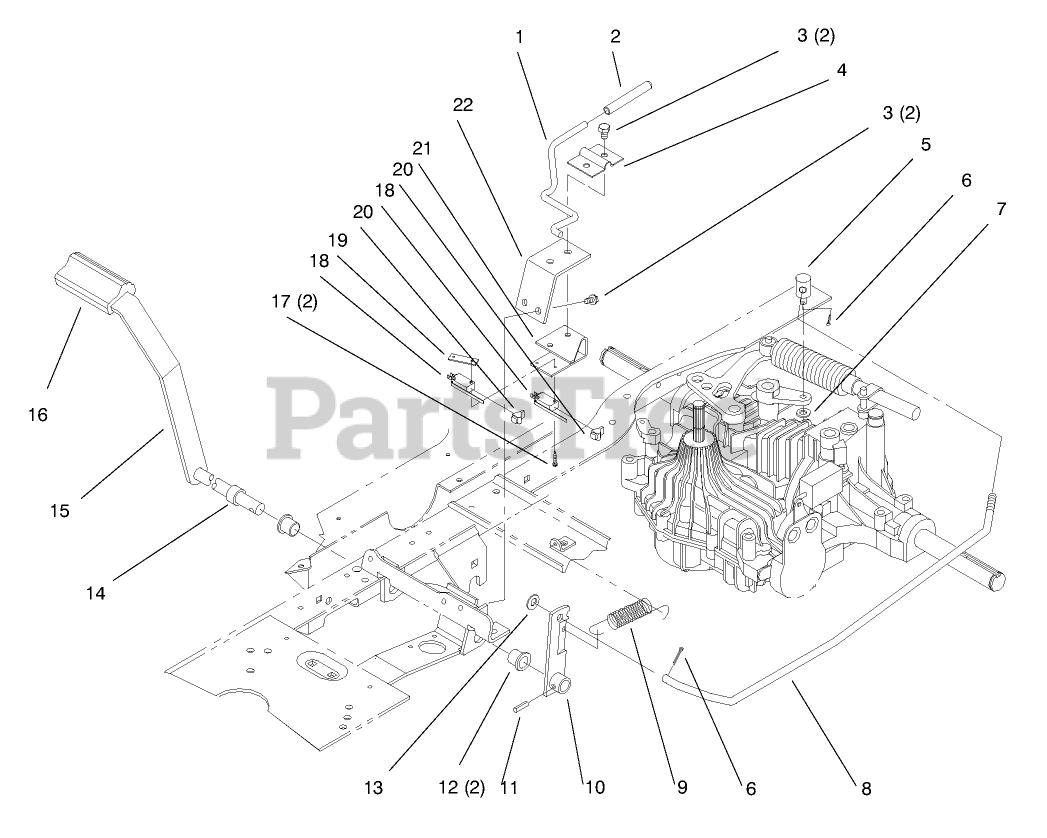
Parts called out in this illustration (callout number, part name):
1	ROD - PARKING BRAKE
2	GRIP - PARKING BRAKE
3	SCREW-HWHTF
4	BRACKET-PARKING BRAKE
5	TRUNNION - BRAKE
6	PIN-COTTER
7	WASHER-PLAIN
10	BRAKE LEVER ASM
11	PIN-SPRING
12	BUSHING-FLANGE
13	WASHER-FLAT
14	SPACER-BRAKE
15	LEVER - BRAKE ASM
16	PAD-PEDAL
17	SCREW-HH
18	SWITCH-MICRO
19	NUT-SPEED
20	PLUNGER-SEAL
21	BRACKET-BRAKE SWITCH
22	SUPPORT-P. BRAKE
